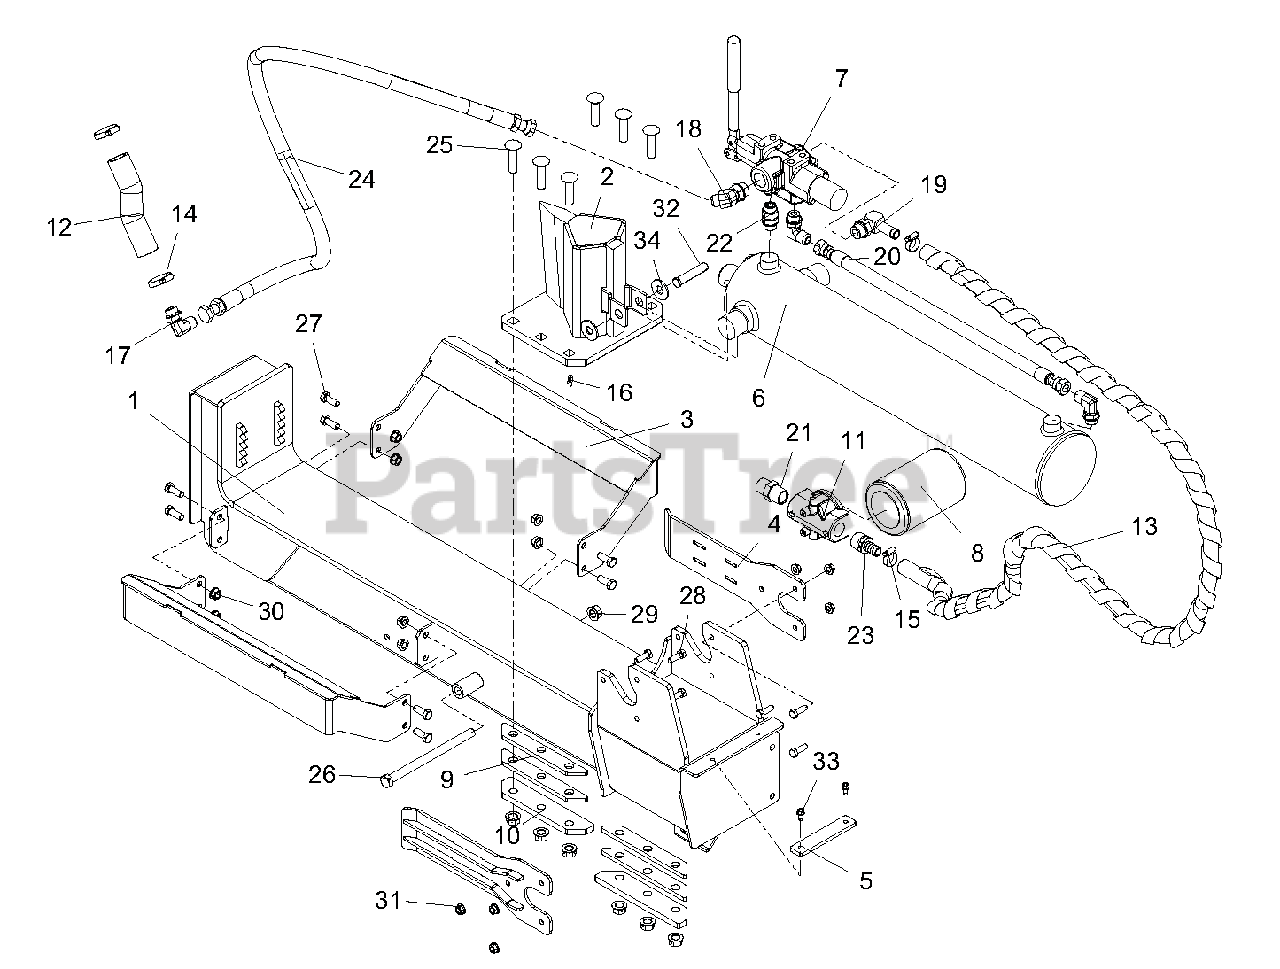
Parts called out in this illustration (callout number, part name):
1	WLDMT, BEAM - 27&34T SPLITTER
2	WLDMT, SPLITTER WEDGE
3	WLDMT, CRADLE, LOG SPLITTER
4	PLATE, STRIPPER
5	SPACER, CYLINDER
6	CYLINDER, SPLITTER-4.5"
7	VALVE CONTROL-SPLITTER
8	FILTER,OIL-W/BYPASS
9	SPACER, WEDGE
10	RETAINER,WEDGE
11	HEAD,FILTER-3/4 NPT BYPASS
12	HOSE, HYD - SUCTION 7.375"
13	HOSE, HYD-RET 801-10 WP 74"
14	CLAMP-HOSE 1.50X.81X1.42
15	CLAMP,.88 DIA. HOSE
16	CLIP, SPRING
17	FTG,HYD 6801-8-8
18	FTG,HYD 6802-8-10
19	FTG,HYD 4601-10-10
20	HOSE, HYD - 22"
21	FTG,HYD 5404-12-12
22	FTG, HYD - STR 08MAORB-08MORB
23	FTG,HYD STRAIGHT 10-12
24	HOSE, HYD - 58"
25	BLT-RDHDSQNKFTH.50-13X2 G8YWZC
26	@BLT-HEX .50-13X7.50 GR5 YWZC
27	@BLT-HEX .38-16X1.00 GR5 YWZC
28	@BLT-HEX .31-18X1.00 GR5 YWZC
29	NUT-LK-CTR-FLG .50-13 YWZC
30	@NUT-LK-TOP-FLG .38-16 YWZC
31	@NUT-LK-TOP-FLG .31-18 YWZC
32	PIN-CLEV .50X2.50X2.27 YWZC
33	SCR-TAP .25-20X.50 HWH TR YWZ
34	@WSHR-FL-STL.563X1.38X.109YWZC
